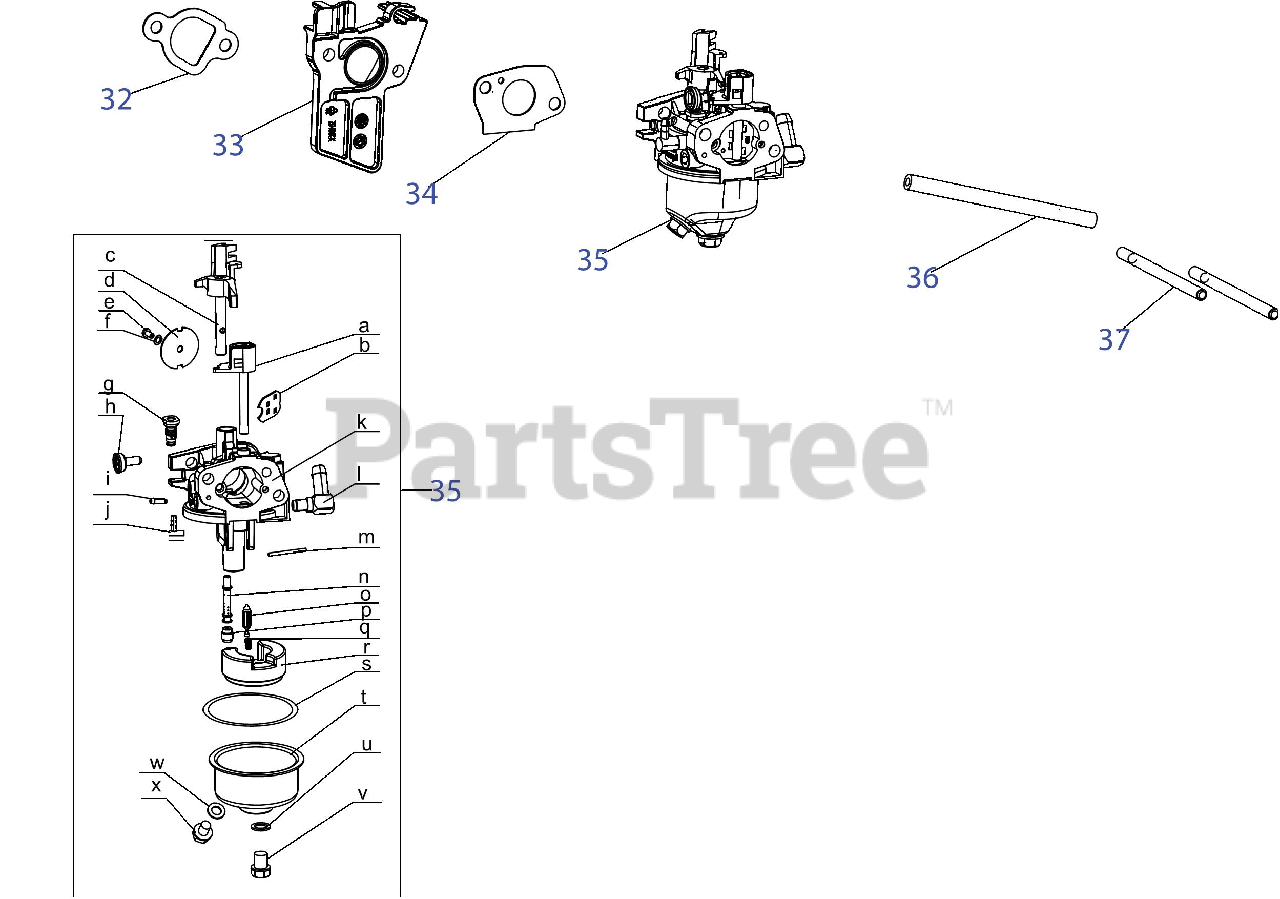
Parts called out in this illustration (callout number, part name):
32	Gasket, Carburetor Insulator
34	Gasket, Carburetor
35	Carburetor
36	Fuel Hose,3.2x6.5x170
37	Stud, M6x92
